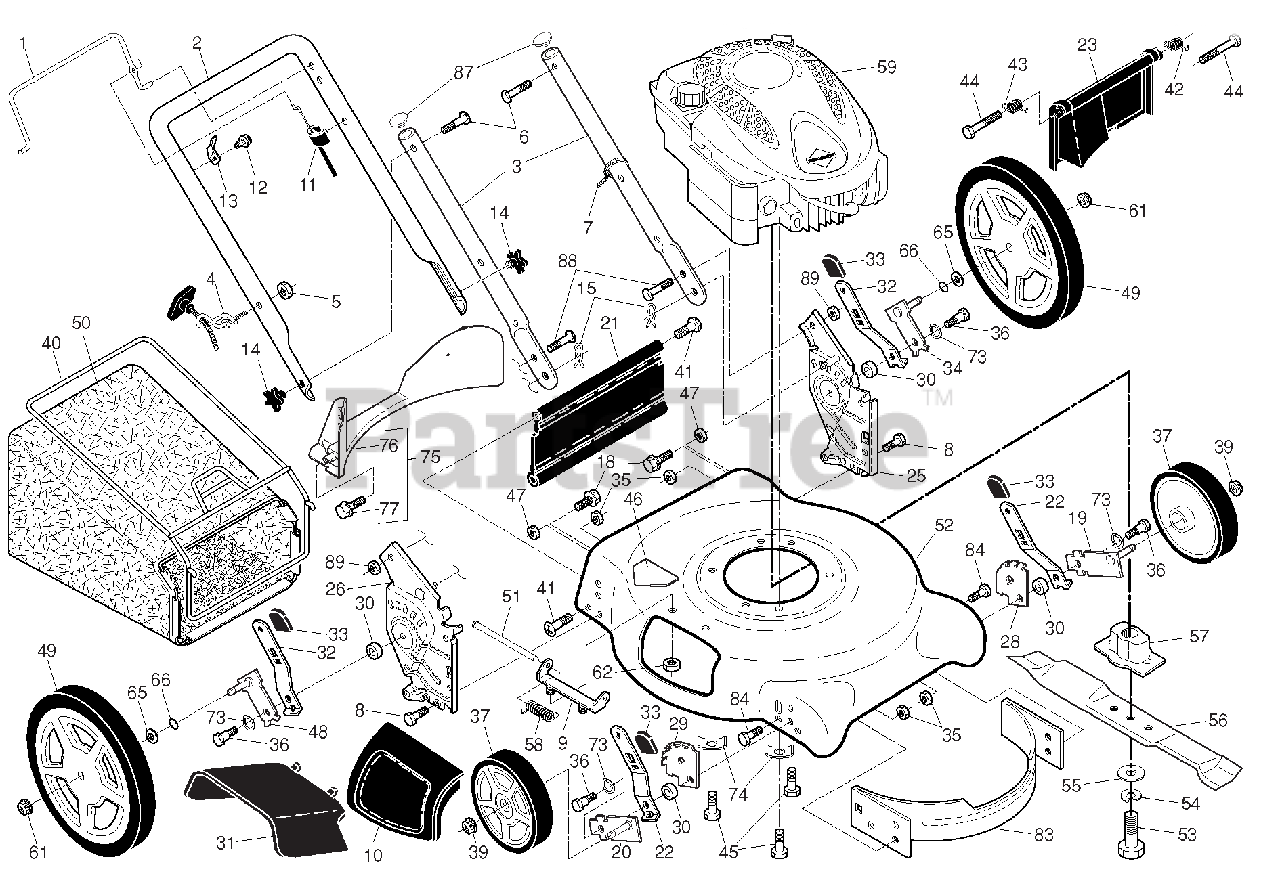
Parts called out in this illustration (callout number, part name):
1	CONTROL BAR
2	UPPER HANDLE
3	BELT KEEPER
4	Rope Guide
5	Nut, Hex
6	Handle Bolt
7	Wire Tie
8	Bolt, Hex Head 5/16-18 x 3/4
9	Hinge Bracket
10	Mulcher Door
11	ENGINE ZONE CONTROL CABLE
12	SCREW, HEX WASHER HEAD
13	UP-STOP BRACKET
14	Handle Knob
15	Hairpin Cotter
18	SCREW.HEX.WASHEAD.1/4-20 X 3/8
19	Axle Arm Assembly, Front, LH
20	Axle Arm Assembly, Front, RH
21	Kit, Rear Skirt
22	Selector Spring, Front
23	Rear Door Assembly
25	HANDLE BRACKET ASSEMBLY, LH
26	HANDLE BRACKET ASSEMBLY, RH
28	Wheel Adjusting Bracket, LH
29	Wheel Adjusting Bracket, RH
31	Discharge Deflector
32	SELECTOR SPRING, REAR
33	Selector Knob
34	Axle Arm Assembly, Rear, LH
35	Locknut, Hex 5/16-18
36	Shoulder Bolt
37	WHEEL & TIRE ASSEMBLY, FRONT
39	Nut, Hex
40	Frame, Grassbag
41	HINGE SCREW
42	Spring, Rear Door, LH
43	Spring, Rear Door, RH
44	Bolt, Rear Door
45	Screw, Hex Head, Threaded, Rol
46	Danger Decal
47	Nut, Hex
48	Axle Arm Assembly, Rear, RH
49	WHEEL & TIRE ASSEMBLY, REAR
50	Grassbag
51	Hinge Rod
52	KIT, LAWN MOWER HOUSING
53	Screw, Hex Head, Grade 8 3/8-2
54	Helical Lockwasher
55	Hardened Washer
56	21" Blade
57	BLADE ADAPTER
58	Hinge Spring
61	Flanged Locknut, Hex
62	Locknut, Hex 1/4-20
65	Washer, Flat
73	Washer, Curved, Cylindrical
74	Washer, Special, Engine
75	Kit, Rear Baffle (Includes 3 S
76	Baffle, Rear
77	Screw, Rear Baffle
83	BAFFLE, FRONT
84	BOLT.5/16-18HEX.WHS.HD.LCKSERR
87	PLUG, HANDLE BAR
88	BOLT, CARRIAGE 5/16-18 X 5/8
89	Nut, Hex, Flangelock
